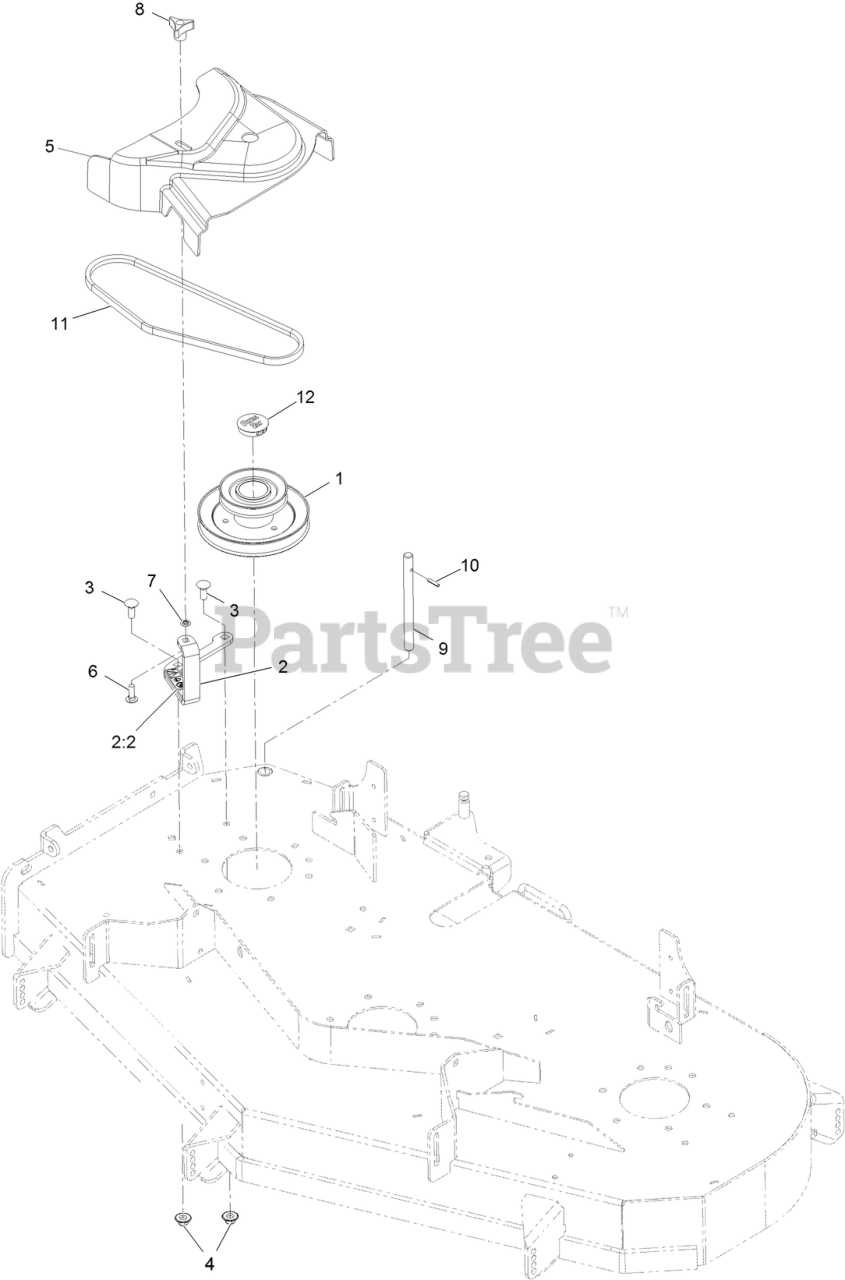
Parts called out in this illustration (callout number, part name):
1	JACKSHAFT,UV DRIVE 524 SPLINED
2	ASM-CVR BRKT W/DECAL
2:2	DECAL-DANGER
3	BOLT-CARR
4	Nut-Nyloc 3/8-16 Flg
5	COVER-BELT, UV 52 ENTRY
6	BOLT-CARR
7	RING-RETAINING, BOLT
8	KNOB-3 PRONG
9	SHAFT-CATCHER, GRASS
10	PIN-ROLL
11	BELT-BLOWER
12	PLUG, BLACK NYLON 1.75
